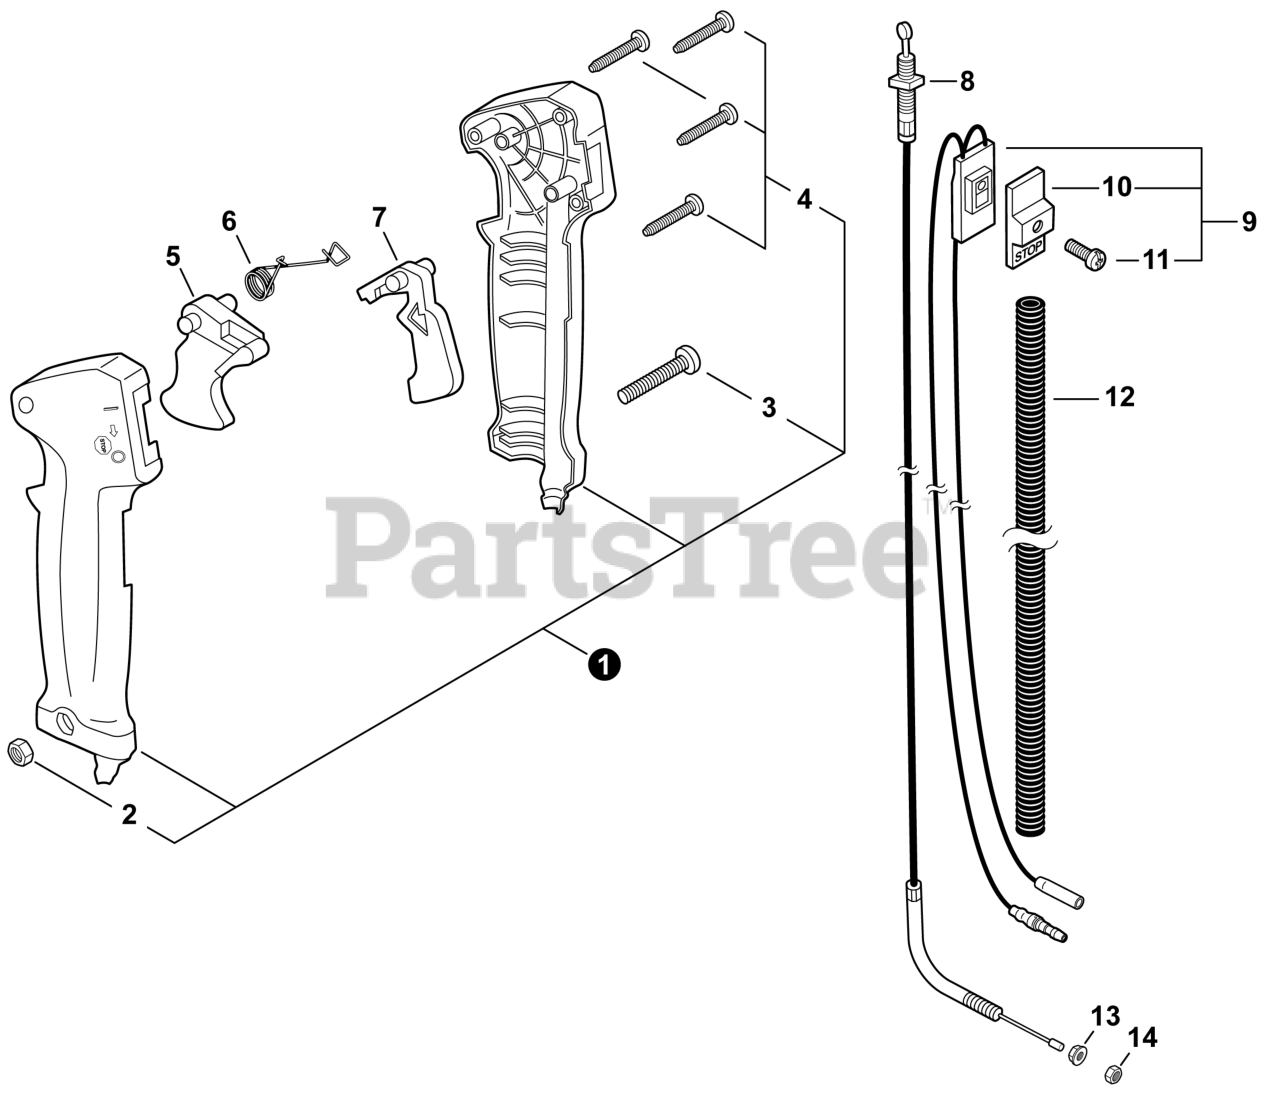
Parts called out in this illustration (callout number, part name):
1	CONTROL HANDLE KIT
3	SCREW 5x30
4	SCREW 3x25
5	TRIGGER, THROTTLE
6	SPRING, TORSION
7	LOCKOUT, THROTTLE
8	CABLE, THROTTLE
9	SWITCH, ON-OFF
10	KNOB, SWITCH - ORANGE
11	SCREW 3x10
12	TUBE, FLEXIBLE 7x790
13	NUT, FLANGE M6
